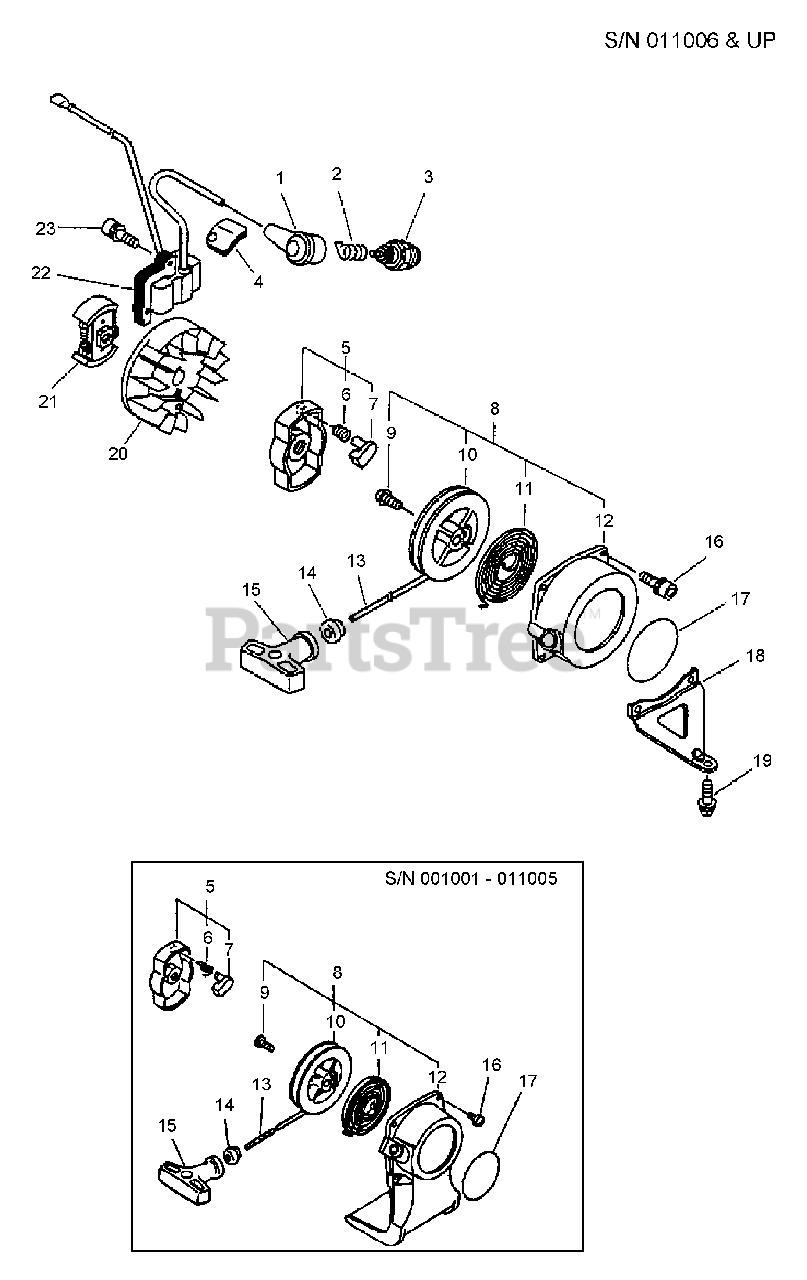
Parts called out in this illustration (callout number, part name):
1	CAP, SPARK PLUG
2	TERMINAL, SPARK PLUG CAP
3	SPARK PLUG -- BPM-7A
4	COVER, DUST
5	STARTER PAWL ASSY
6	SPRING, RETURN
7	PAWL, STARTER - BLACK
8	STARTER ASSY
10	REEL, ROPE
11	SPRING, REWIND
12	CASE, STARTER - BLUE
12	CASE, STARTER
13	ROPE, STARTER - 3X990
14	GUIDE, ROPE
15	GRIP, STARTER
16	SCREW - 4X16
17	LABEL - ECHO
18	SUPPORT, REAR HANDLE
19	SCREW - 5X16
20	FLYWHEEL
21	CLUTCH ASSY
22	COIL, IGNITION
23	SCREW - 4X22
